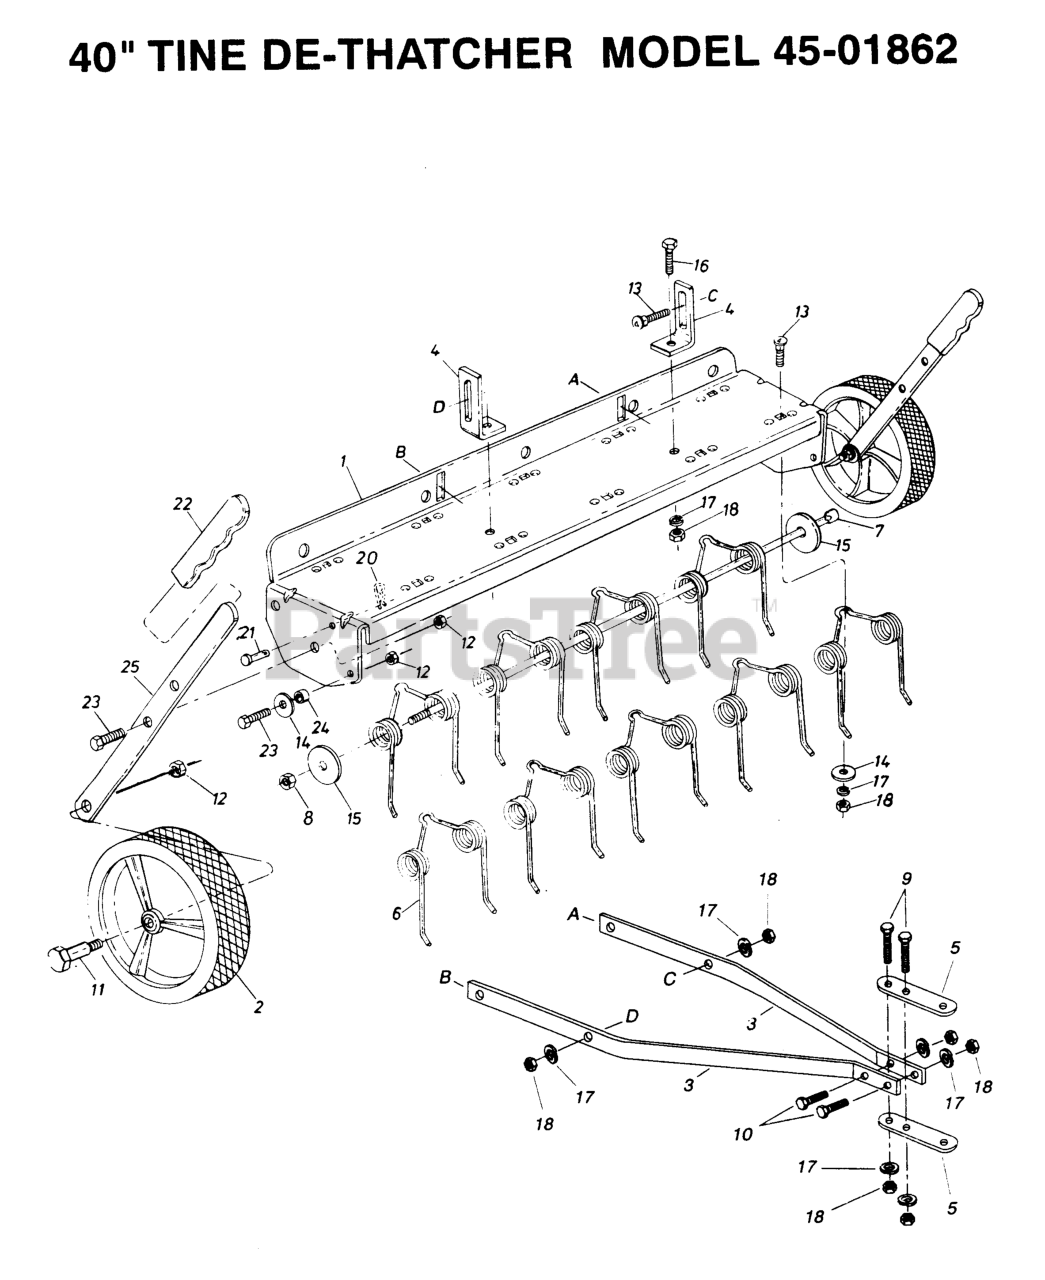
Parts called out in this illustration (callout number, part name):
5	BRACKET THATCHER
6	SPRING TINE
9	Bolt Fin Hex 5/16 - 18 Unc x 2 Gr. 2
10	BOLT.5/16-18X1-1/4 FULL.THREAD
14	WASHER
16	BOLT.FIN.HEX.5/16-18X3/4
22	Rubber Grip
